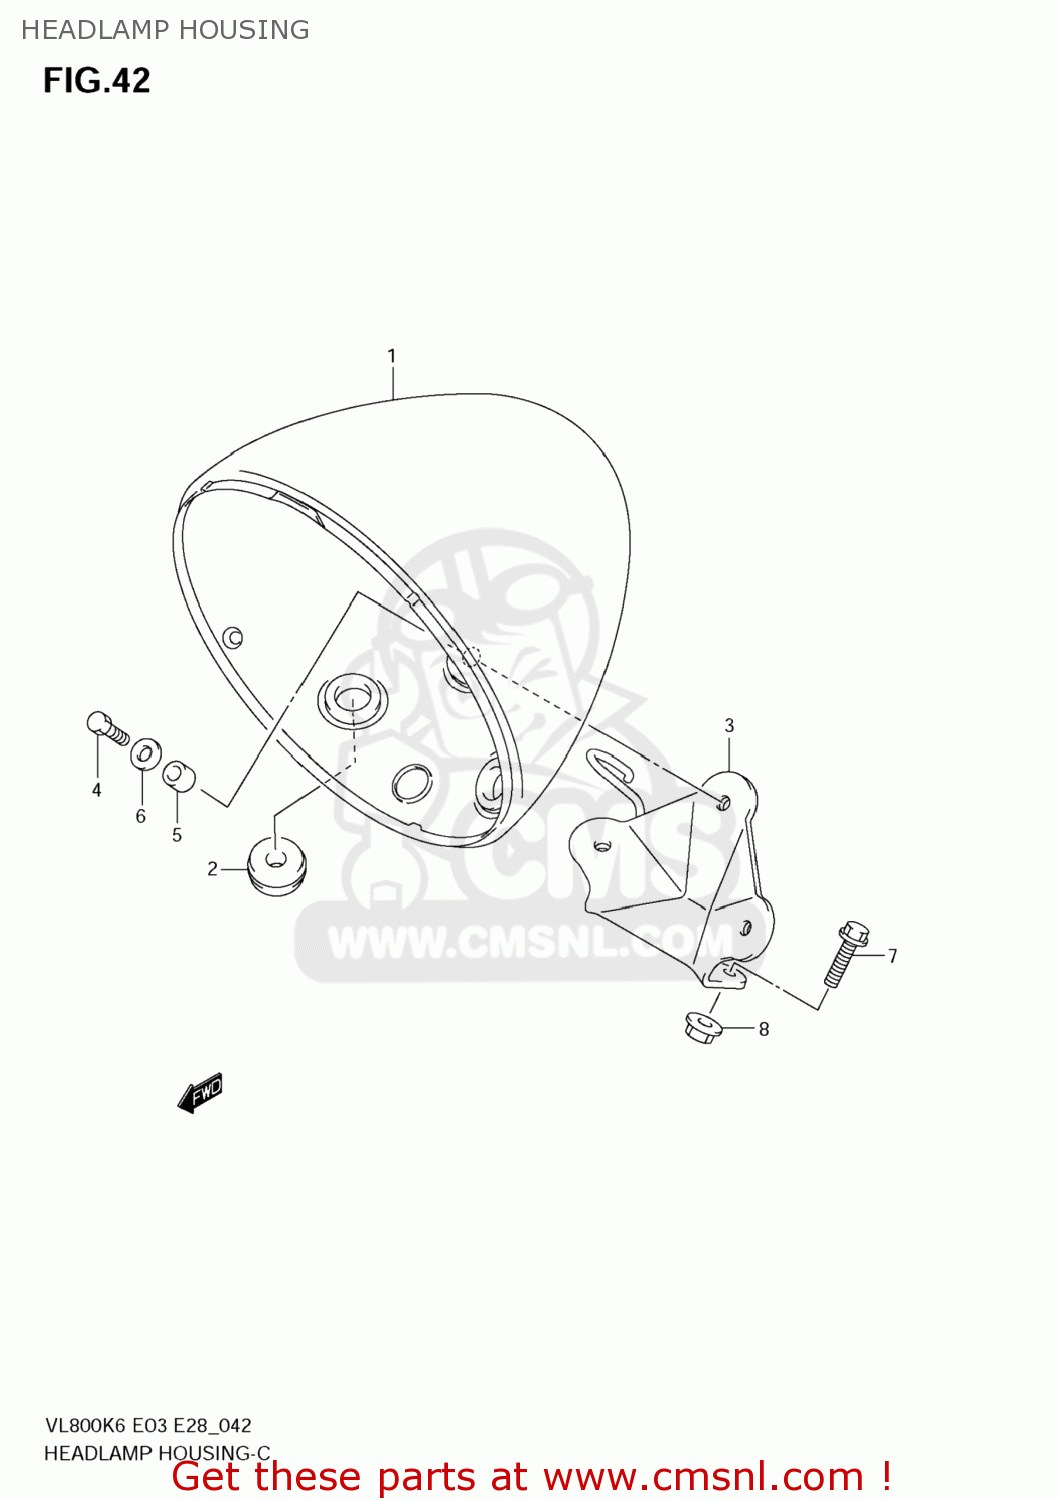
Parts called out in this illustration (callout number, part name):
1	HOUSING ASSY,HEADLAMP
2	CUSHION
3	BRACKET,HEADLAMP HOUSING
4	BOLT
5	SPACER(6.5X9X10)
6	WASHER(6.5X20X1.2)
7	BOLT
8	NUT
